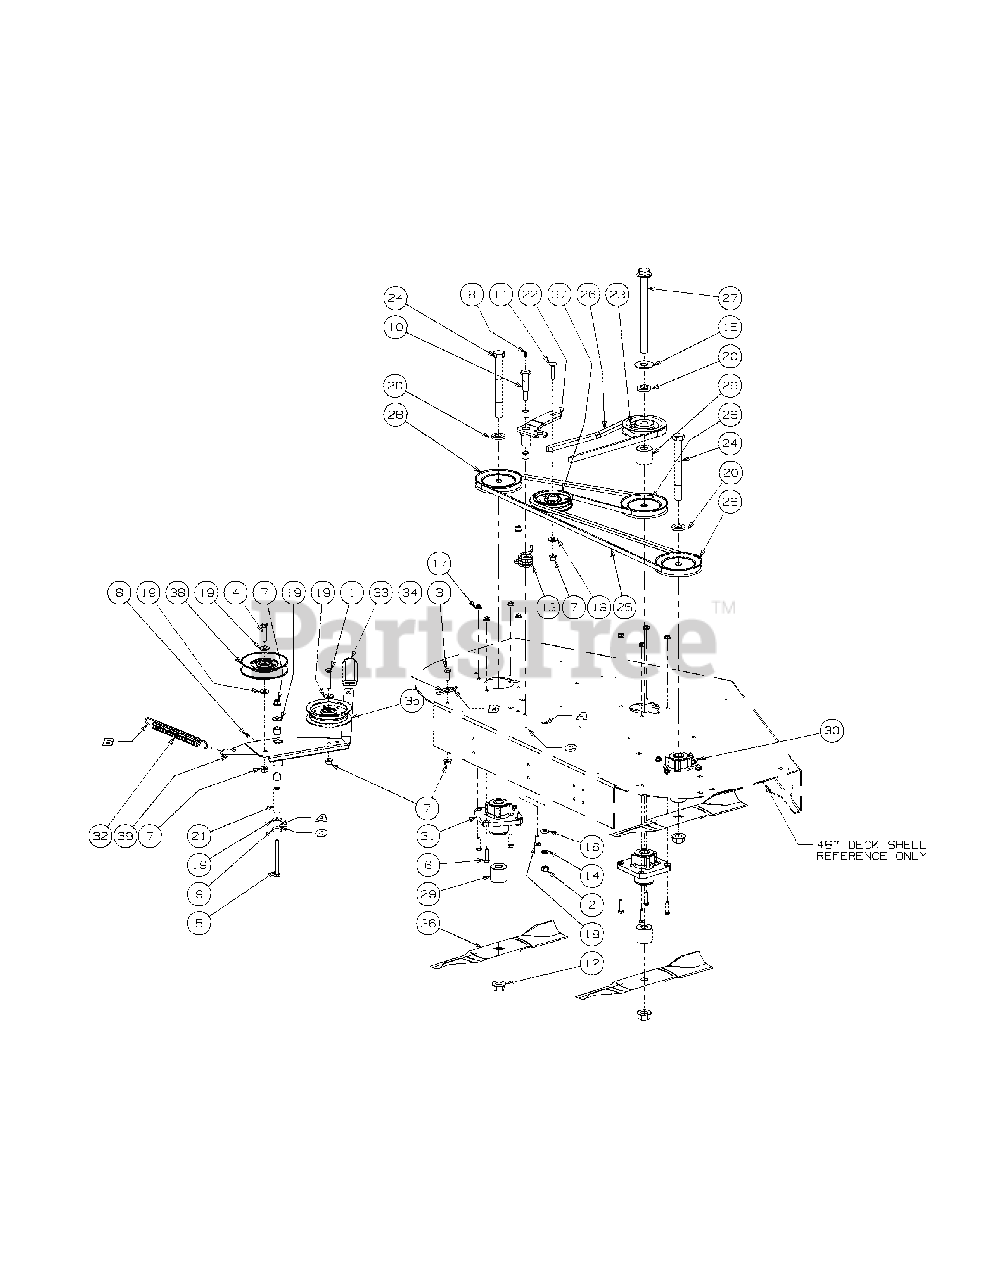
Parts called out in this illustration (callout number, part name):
1	Hex Cap Screw, 3/8-16 x 2.00
2	Hex Nut, 7/16-14
3	Hex Cap Screw, 3/8-16 x 1.00
4	Hex Cap Screw, 3/8-16 x 1-3/4
5	Hex Cap Screw, 3/8-16, 4.00
6	HHCS, 5/16-18 x 1-1/4
7	Flange Lock Hex Nut, 3/8-16
8	Grease Fitting, 1/4-28 x 3/16
9	Idler Washer
10	Shoulder Screw, 7/16-14
11	Hex Carriage Screw, 3/8-16, 1.75
12	Flange Hex Nut, 3/4-16
13	Torsion Idler Spring
14	Lock Washer, 7/16
15	Flat Washer, .781 ID 2.00 OD, .105
16	Flat Washer, .469 ID, .875 OD, .105
17	Nut, 5/16-18, Flange Lock
18	Carriage Bolt, 3/8-16 x 1
19	Flat Washer, .406 ID, 1.0 OD, .105
20	Spacer .812 ID x .268 LG
21	Spacer, .39 ID x .625 OD x 2.75
22	Idler Arm Assembly includes:
23	V-Pulley, 4.75 OD
24	Hex Cap Screw, 3/4-16, 6.50
25	V-Belt, A Section x 105.3
26	V-Belt, B Section x 86.2
27	Hex Cap Screw, 3/4-16, 9.00
28	V-Pulley, 4.9 OD
29	Spacer, .760 ID x 1.75 OD x 1.60
30	Grease Fitting, 45 Degree
31	Spindle Assembly
32	Extension Spring, .94 OD x 7.57
33	Idler Tension Handle Grip
34	Tension Spring Bracket
35	Idler Pulley, 4.06 OD w/Deep Flange
36	Blade, 17.0, Hi-Lift, 0.756 ID
37	Idler Pulley, 4.06 Dia.
38	Idler Pulley, 5.06 Dia.
39	Idler Arm Assembly includes:
